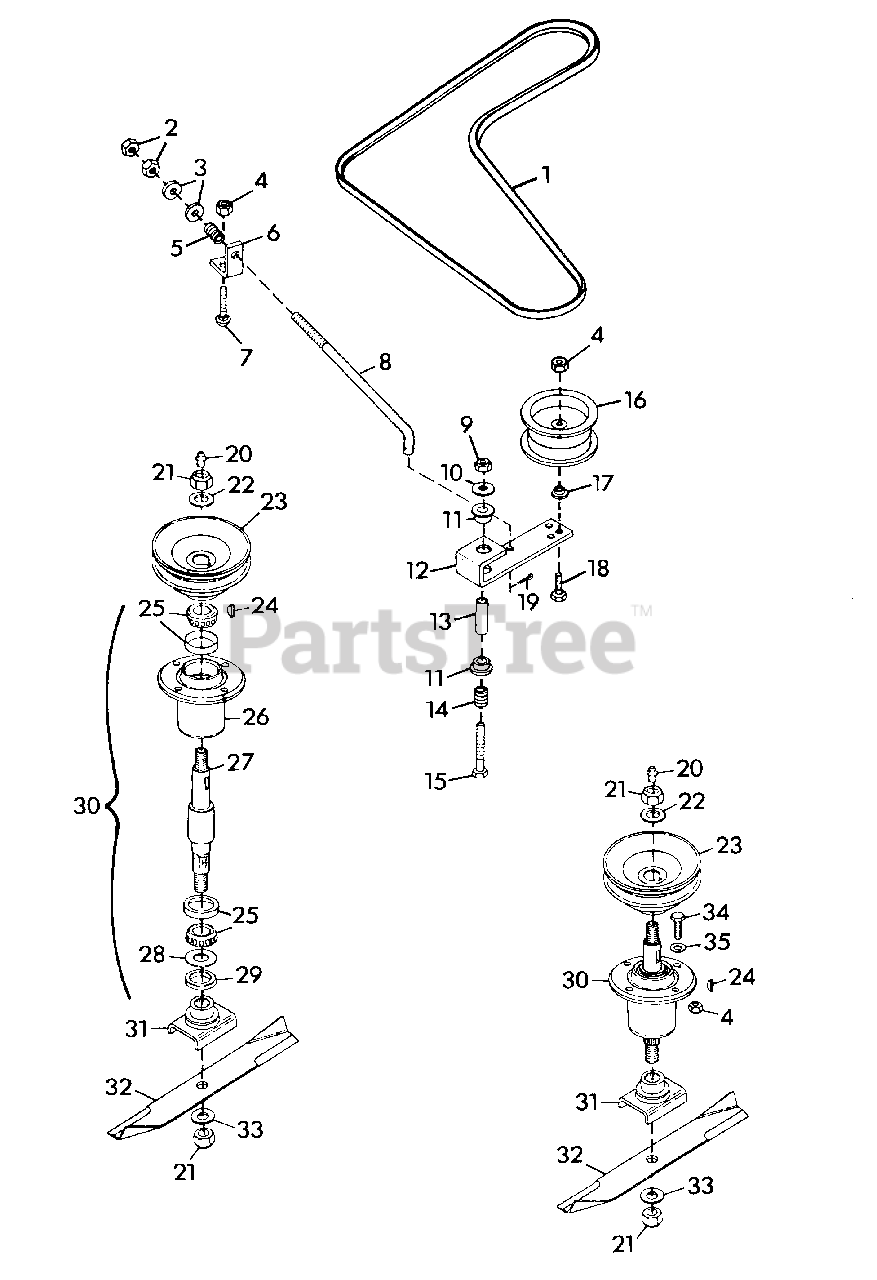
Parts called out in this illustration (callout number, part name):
1	BELT, PRO-36 MOWER
2	NUT, HEX 3/8-24
3	WASHER, FLAT .406X.812X.065
4	NUT, LOCK 3/8-16
5	SPRING, COMPRESSION 1X.78X338 LB/N
6	BRACKET, BELT TENSIONER
7	BOLT, 3/8-16X1.00 RD HD SQ NK
8	ROD, IDLER
9	NUT, LOCK 1/2-13
10	WASHER, FLAT .531X1.250X.100
11	BUSHING, NYLON .760X1.00X.600 FLG.
12	ARM, IDLER PIVOT
13	SPACER
14	SPRING, COMPRESSION 1X.80X36 LB/N
15	BOLT, HEX 1/2-13X3.25
16	PULLEY, IDLER
17	BUSHING
18	BOLT, HEX 3/8-16X2.25
19	PIN, COTTER .09X.75
20	FITTING, LUBE 1/8
21	NUT, LOCK 5/8-11
22	WASHER, FLAT .687X1.312X.122
23	SHEAVE, SPINDLE
24	KEY, WOODRUFF 1/4X1 HARD #15
25	ASSEMBLY, BEARING
26	HOUSING, BEARING
27	SHAFT, SPINDLE
28	WASHER, FLAT .975X1.970X.030
29	SEAL, STEEL
30	ASSEMBLY, SPINDLE
31	WELDMENT, BLADE CRADLE
32	BLADE, 36" MOWER
33	WASHER, FLAT .656X1.312X.095
34	BOLT, HEX 3/8-16X1.250
35	WASHER, FLAT .438X1.00X.083
